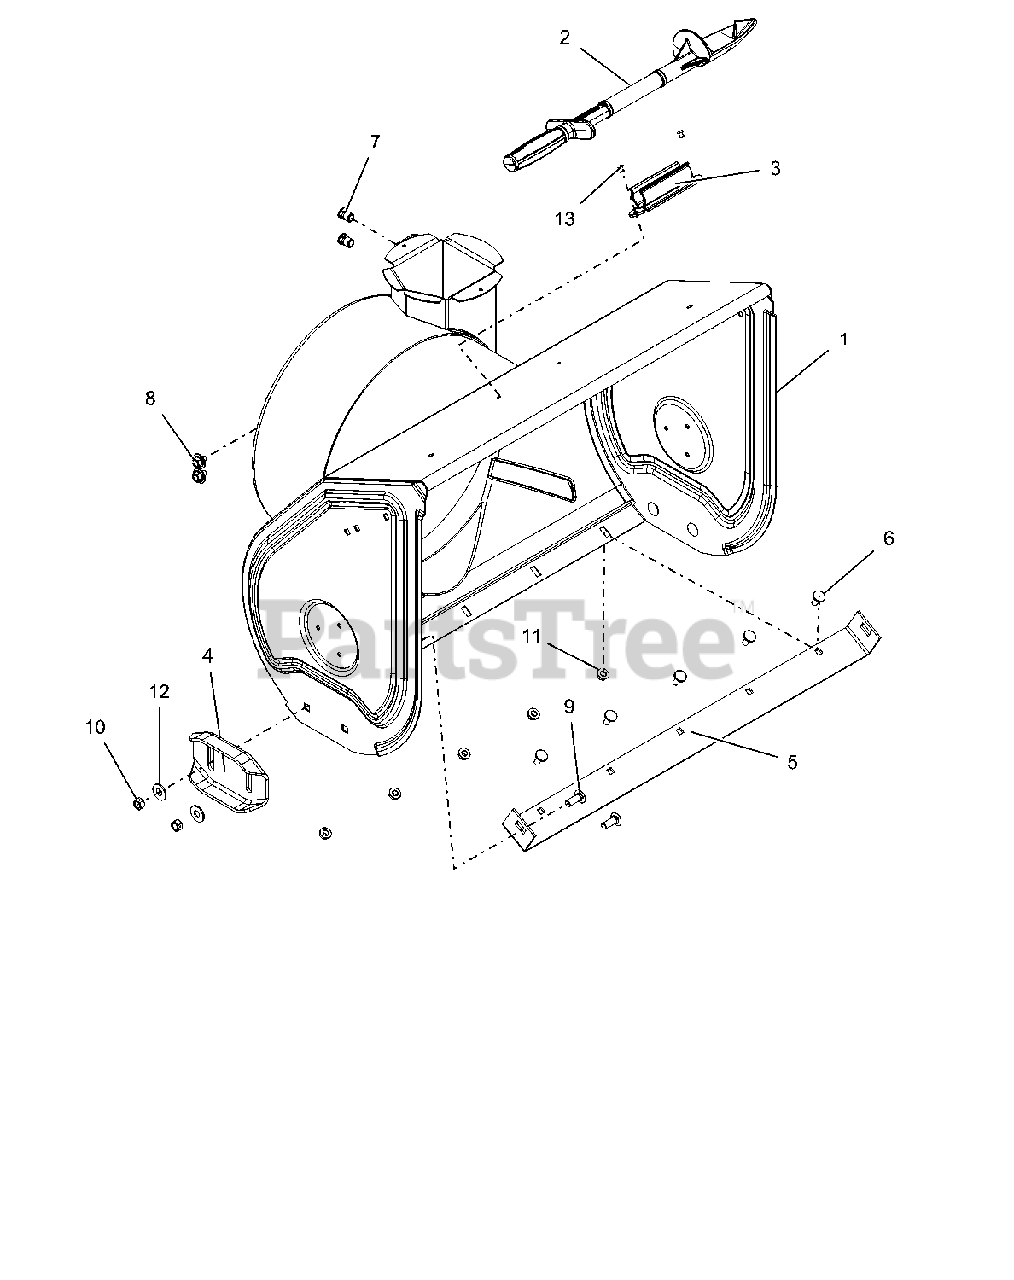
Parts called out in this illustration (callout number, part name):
1	BLOWER HOUSING, 28"
2	DEVICE, SNOW CLEAN OUT
3	MOUNT, SNOW CLEAN OUT
4	SKID SHOE, REVERSIBLE - ORANGE
5	BLADE, SCRAPER - 28"
6	BOLT, MODIFIED HEAD CARRIAGE
7	NUT, THREADED INSERT .38-16
8	SCR-TAP.31-18X.50 HWH TR YWZ
9	@BLT-RDHDSHSQNK.38-16X1.0 G5YZ
10	@NUT-LK-CTR .38-16 YWZC
11	@NUT-LK-TOP-FLG .31-18 YWZC
12	@WSHR-FL-STL.438X1.00X.083 YWZ
13	RVT-POP .187 YZ
